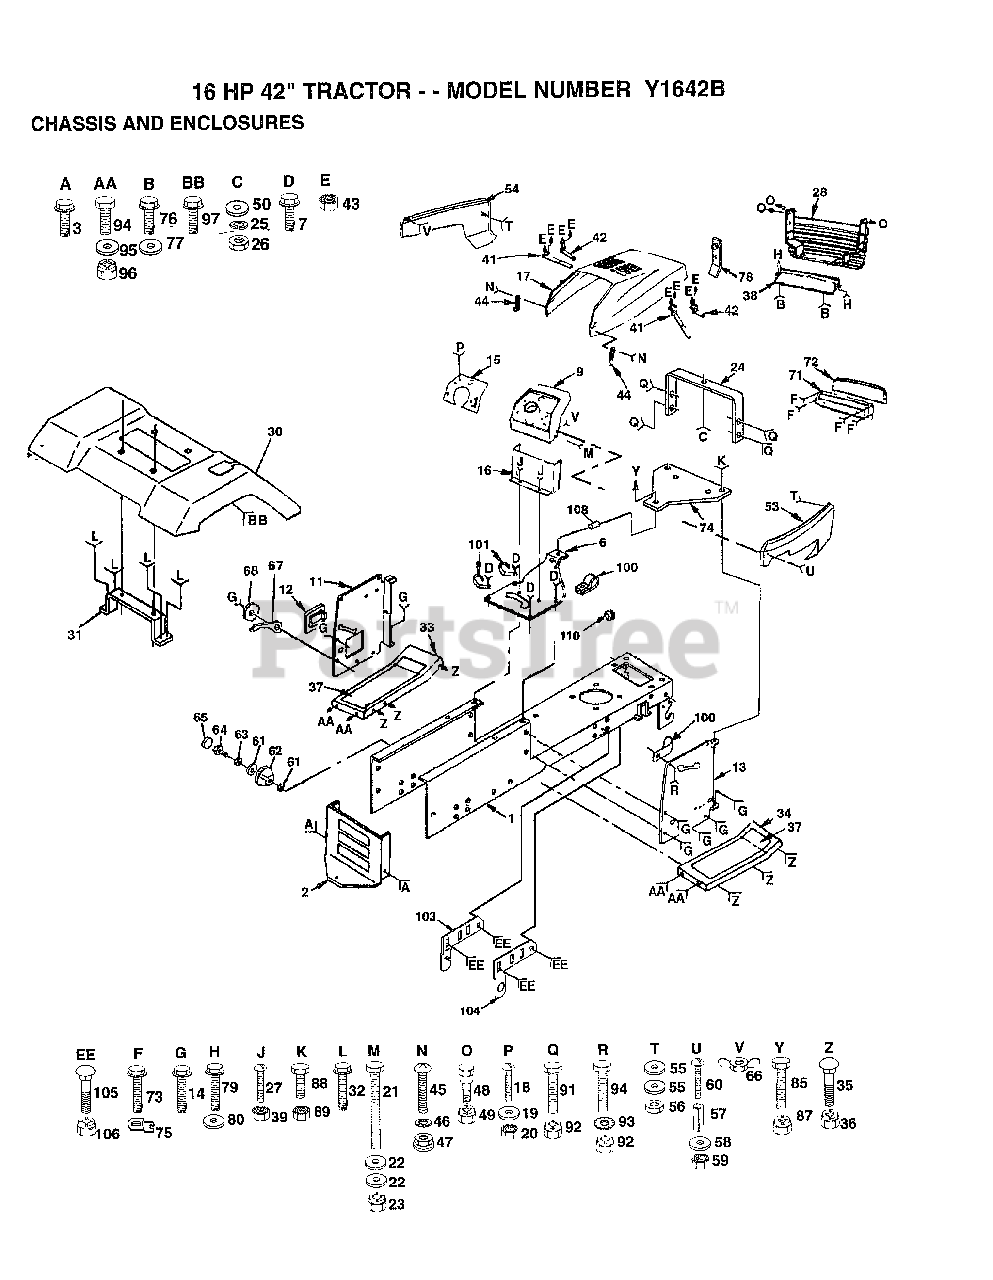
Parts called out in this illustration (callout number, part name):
6	SADDLE.LT.GOOSE
7	SCREW LT
11	PANEL.DASH.LH
12	COVER ACCESS
13	PANEL.DASH.RH
14	SCREW
16	DASH ASSY LT
18	SCREW
19	WASHER
22	WASHER
24	SUPPORT ASS'Y
25	LOCKWASHER
27	SCREW
31	BRKT FENDER
32	SCREW
35	BOLT
37	FOOTREST PAD
43	NUT
44	HOOD LATCH T
45	SCREW
46	LOCKWASHER
47	WELDNUT
50	WASHER PM
54	"PANEL,SIDE LH"
55	WASHER PM
57	SPACER LT
58	WASHER
60	SCREW
61	WASHER
62	HEIGHT INDICATOR
63	LOCKWASHER
65	"PLUG,HOLE"
67	POINTER HGT IND
68	WASHER T
72	LENS LT
75	"""J"" FASTENER LT"
76	SCREW
77	WASHER
79	SCREW HEX CRT
80	WASHER
85	BOLT
89	NUT
93	LOCKWASHER
95	WASHER
97	SCREW LT
100	CLIP T
101	"CLIP,INSULATOR"
103	PIVOT BRKT LH
104	PIVOT BRKT RH
106	NUT
108	SPACER
